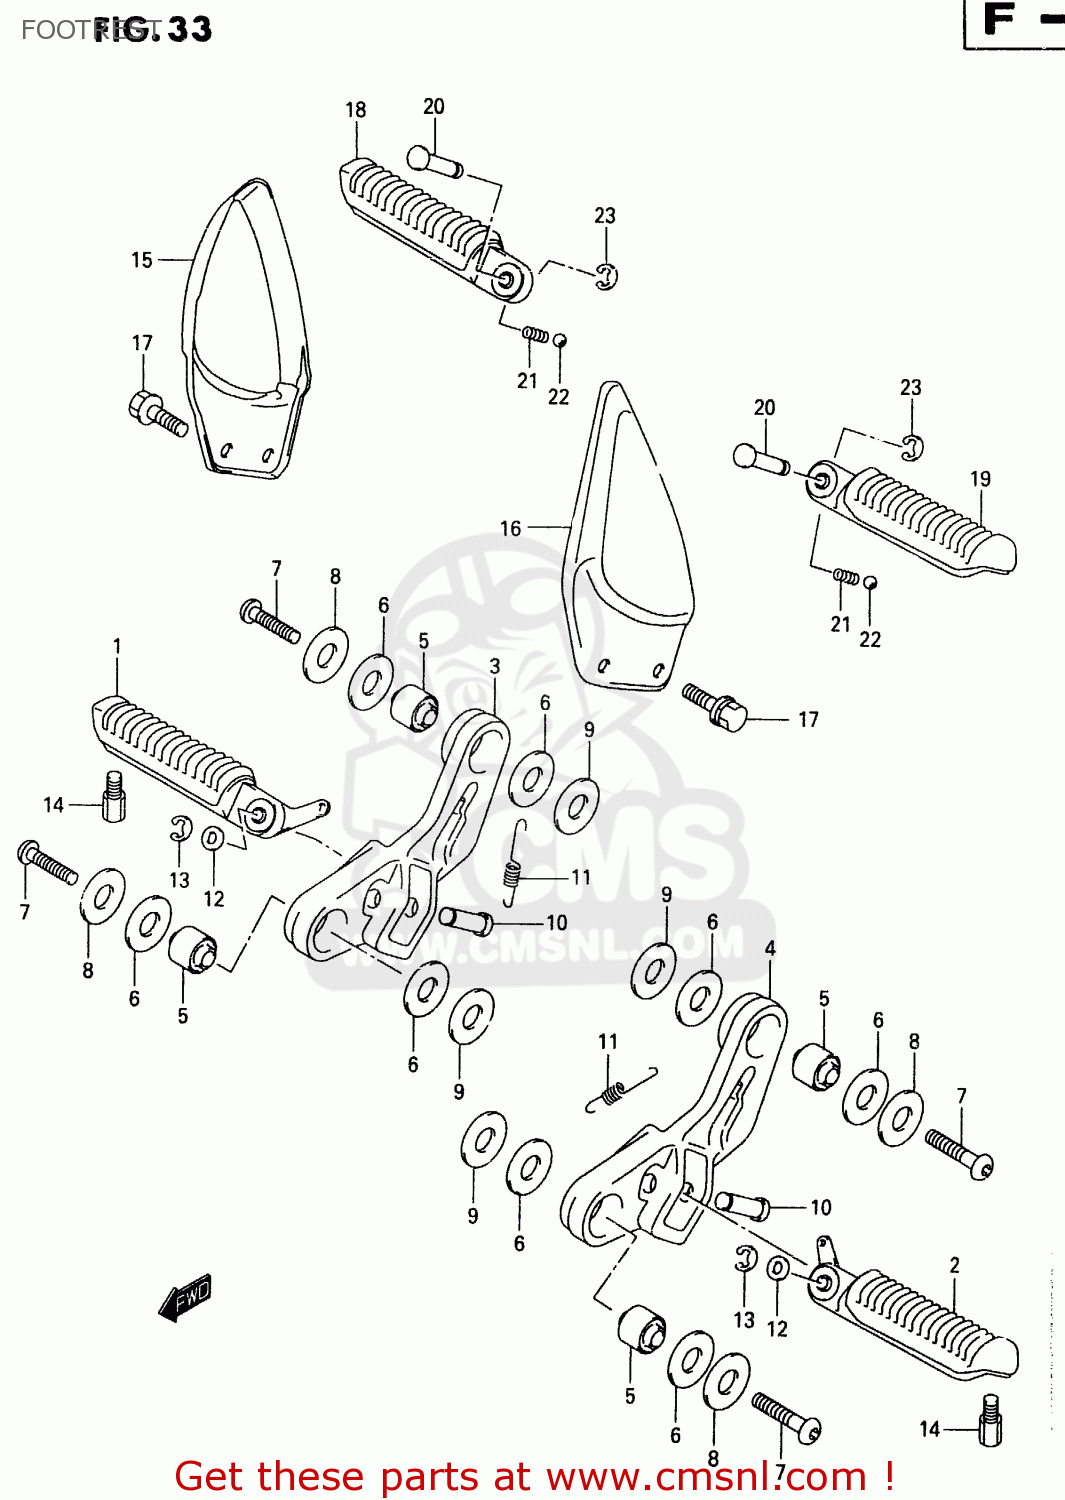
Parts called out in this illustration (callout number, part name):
1	BAR,FRONT FOOTREST,RIGHT
2	BAR,FRONT FOOTREST,LEFT
3	HOLDER,FR FOOTREST,R
4	HOLDER,FR FOOTREST,L
5	BUSH(8.4X20X18)
6	WASHER(12.5X30X2)
7	BOLT(8X33)
8	WASHER (8.5X30X2.3)
9	WASHER(8.5X30X2.3)
10	PIN(8X33.2)
11	SPRING
12	WASHER
13	E.RING
14	BOLT,BANK SENSOR
15	GUARD,FR FOOTREST,R
16	GUARD,FR FOOTREST,L
17	BOLT(8X16)
18	BAR,PILLION FOOTREST,RIGHT
19	BAR,PILLION FOOTREST,LEFT
20	PIN
21	SPRING
22	BALL
23	E.RING
